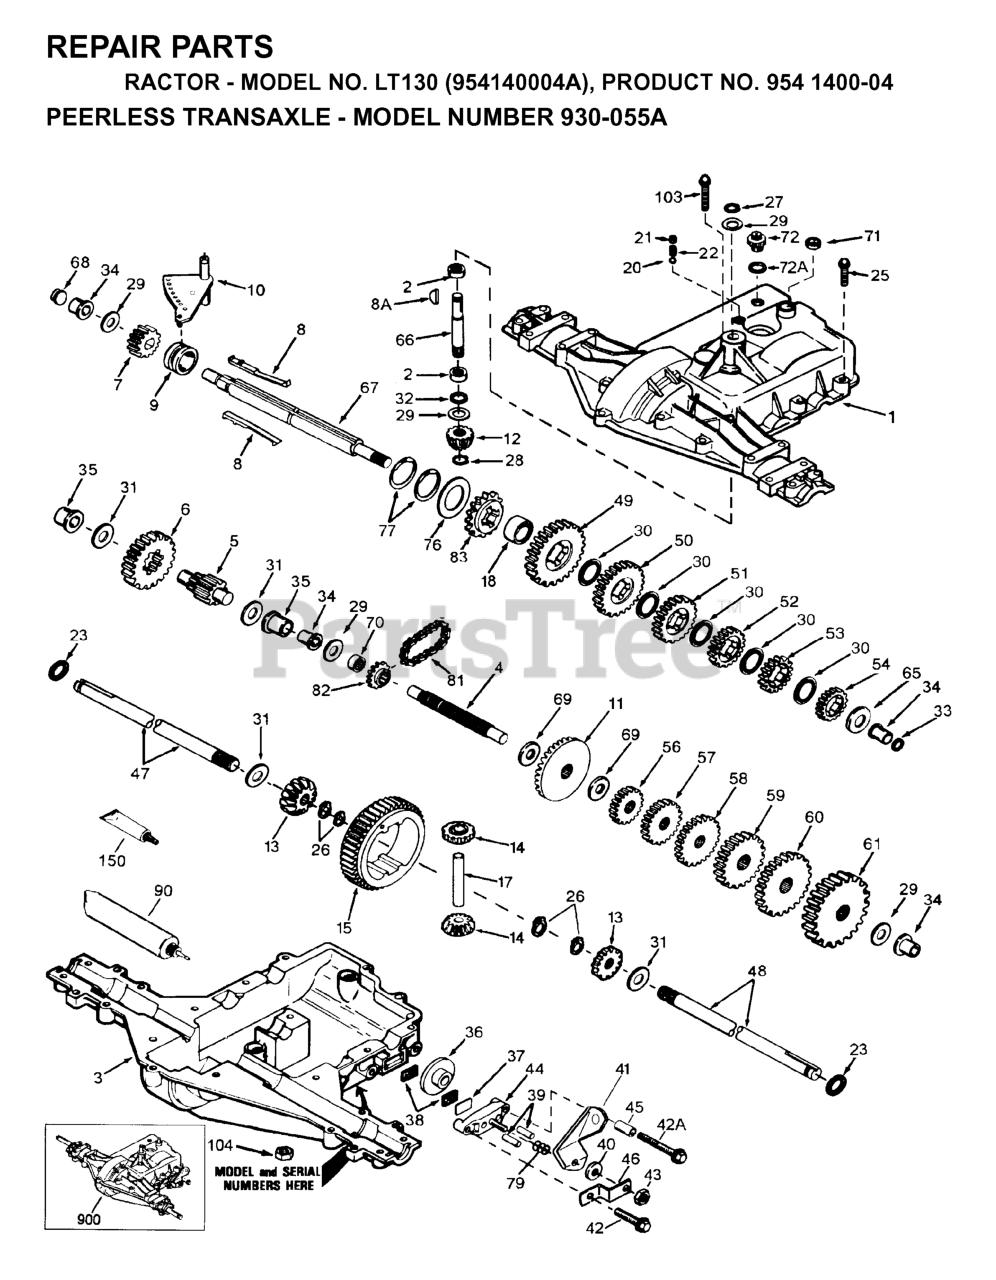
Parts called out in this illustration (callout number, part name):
2	Bearing, Needle
4	Shaft, Counter
8A	Woodruff Key No. 9
9	Collar, Shifter
11	Bevel Gear (42 teeth-steel)
15	Gear, Ring
18	Spacer, Neutral
20	Ball, Steel 5/16" diameter
21	Set Screw 3/18-16 x 3/8"
23	Ring, Seal
25	Screw, Flanged Hex Head, Thread Forming 1/4-20 x 1-1/4
26	Ring, Retainer (4 Required, Package of 2)
27	Retaining Ring
28	Ring, Retaining
29	Washer, Thrust
30	Washer, Thrust
31	Washer (.056 wide)
33	Seal, Square Cut
36	Disk, Brake
37	Plate, Brake pad
38	Brake Pad (pkg of 2)
39	Pin, Dowel
40	Washer, Flat
41	Lever, Brake
42A	Screw, 1 /4-20 x 2-1 /4"
43	Lock Nut 5/16-24
44	Holder, Brake pad
45	Spacer (1/2" OD)
46	Bracket, Brake lever
47	Axle (11-15/16" long)
48	Axle (16-1/2" long)
49	Gear, Spur, 37 Teeth, Steel (1 st)
54	Gear, Spur, 19 Teeth, Steel (4 th)
56	Gear, Spur, 12 Teeth (1 st)
61	Gear, Spur, 31 Teeth (5 th)
66	Input Shaft (3.687" long)
69	Thrust Washer (.762 ID)
71	Seal, Square Cut
76	Washer, Thrust
77	Ring, Retaining, Inverted (Package of 2)
79	Piston Assembly
81	Chain, Roller (Number 41 Chain, 24 Links)
150	Gasket Eliminator (Loctite No. 515)
